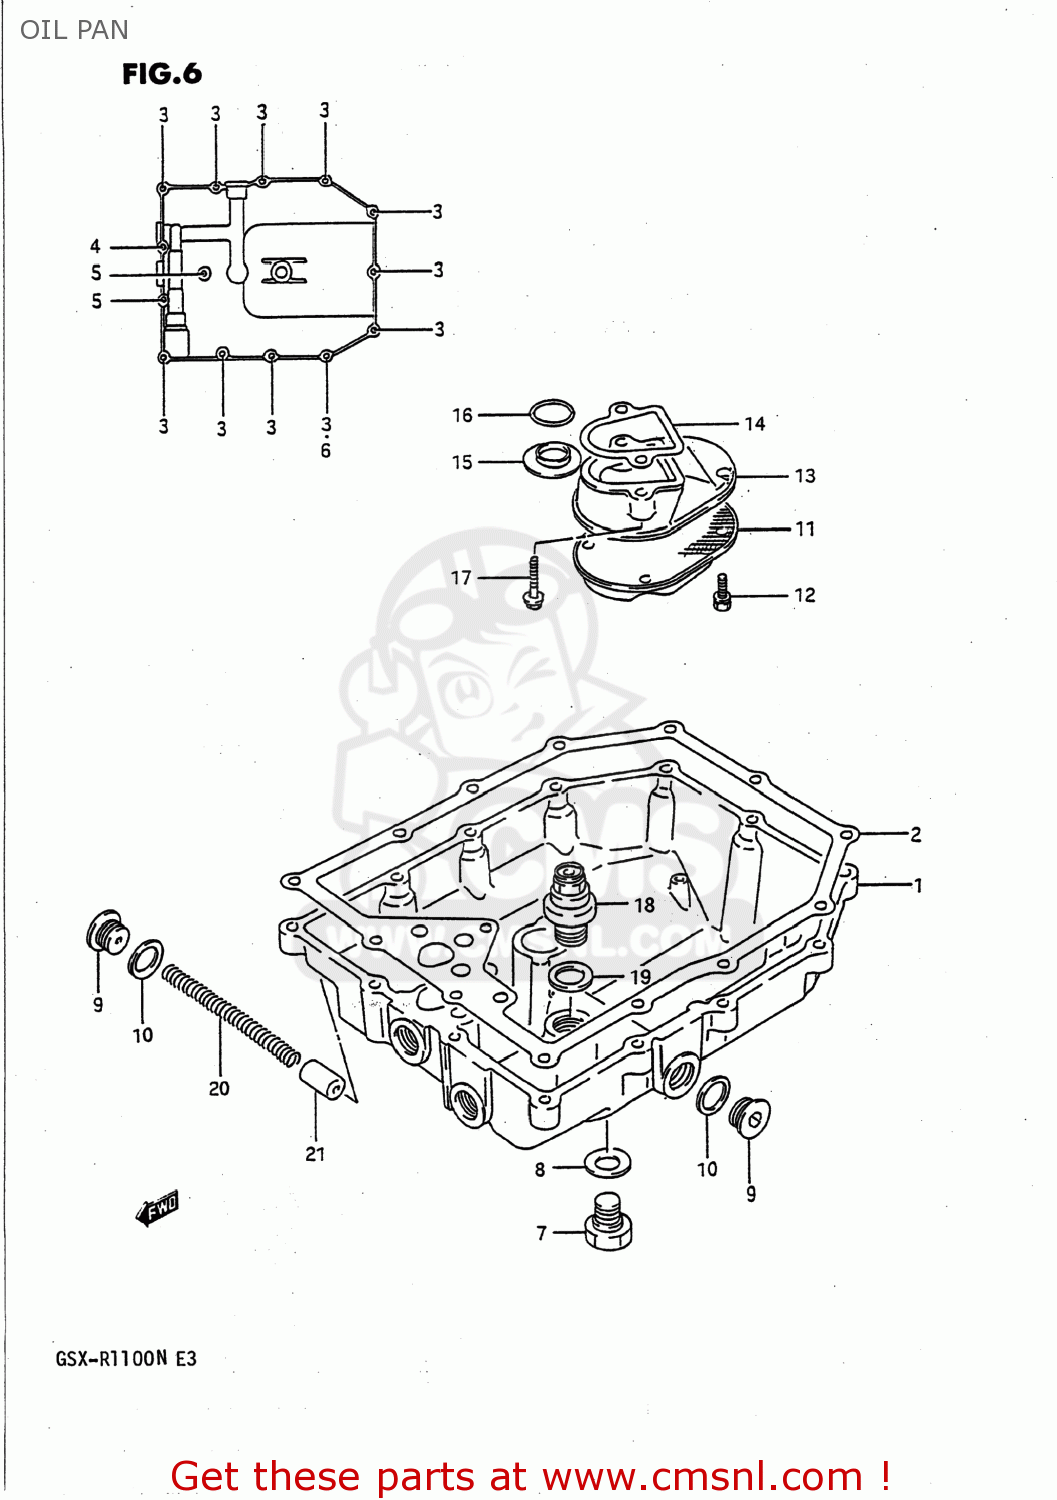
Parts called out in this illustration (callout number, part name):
1	PAN,OIL
2	GASKET,OIL PAN (NAS)
3	BOLT
4	BOLT
5	BOLT
6	GASKET(5.8X11X1.2) (NAS)
7	PLUG
8	GASKET(14X19.2X2) (NAS)
9	PLUG
10	GASKET(16X22X2) (NAS)
11	STRAINER,ENGINE OIL
12	BOLT
13	PROTECTOR,OIL STRAINER
14	O-RING
15	GASKET,OIL OUTLET (NAS)
16	O RING(D:3.2,ID:17.8)
17	BOLT 6X25
18	VALVE ASSEMBLY,OIL RELIEF
19	GASKET(16X22X2) (NAS)
20	SPRING
21	PLUNGER,OIL CONTROLL
